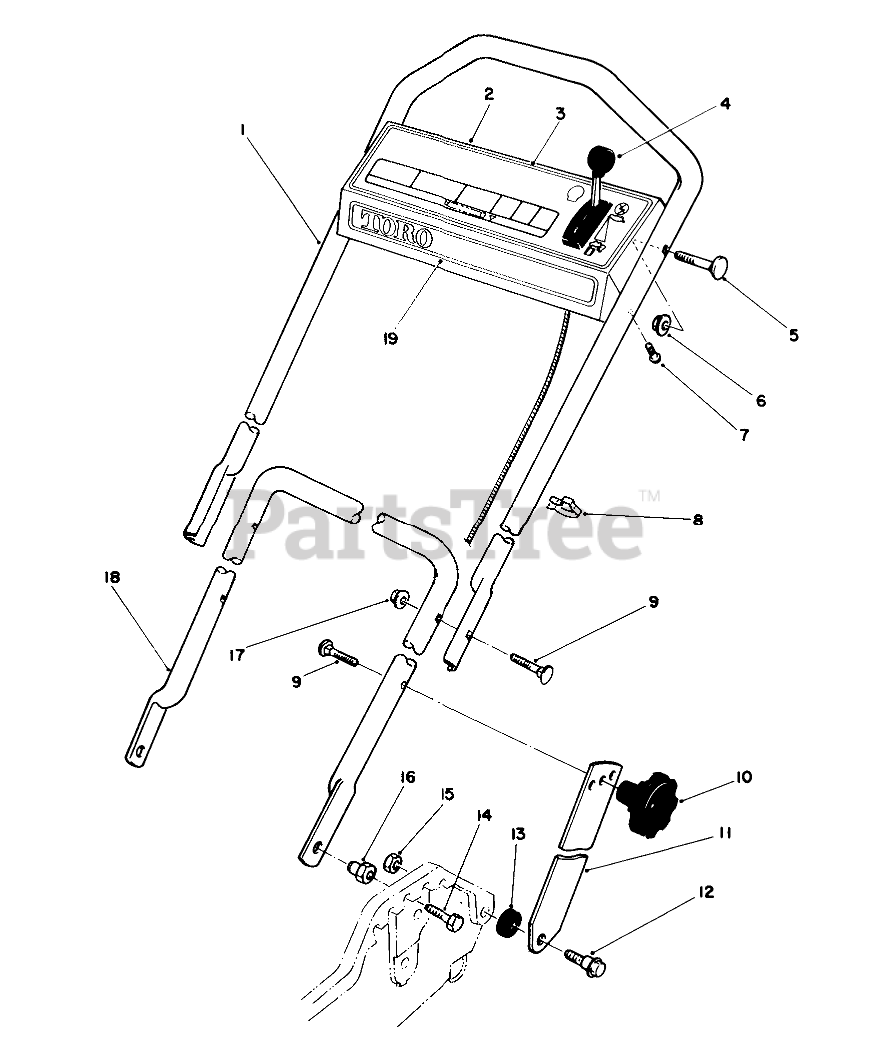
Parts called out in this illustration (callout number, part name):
1	UPPER HANDLE
2	Cover-Control (Incl. Ref. #3)
4	THROTTLE CONT-SERVICE
5	HANDLE SCREW
6	NUT-LOCK, HHF
7	SCREW-HWHTF
9	SCREW
11	Handle Latch
12	SCREW-SHOULDER
13	SPACER
14	SCREW-HH
15	NUT-LOCK, NI
16	HANDLE PIVOT NUT
17	NUT-LOCK, NI
18	LOWER HANDLE
19	Decal-Toro
